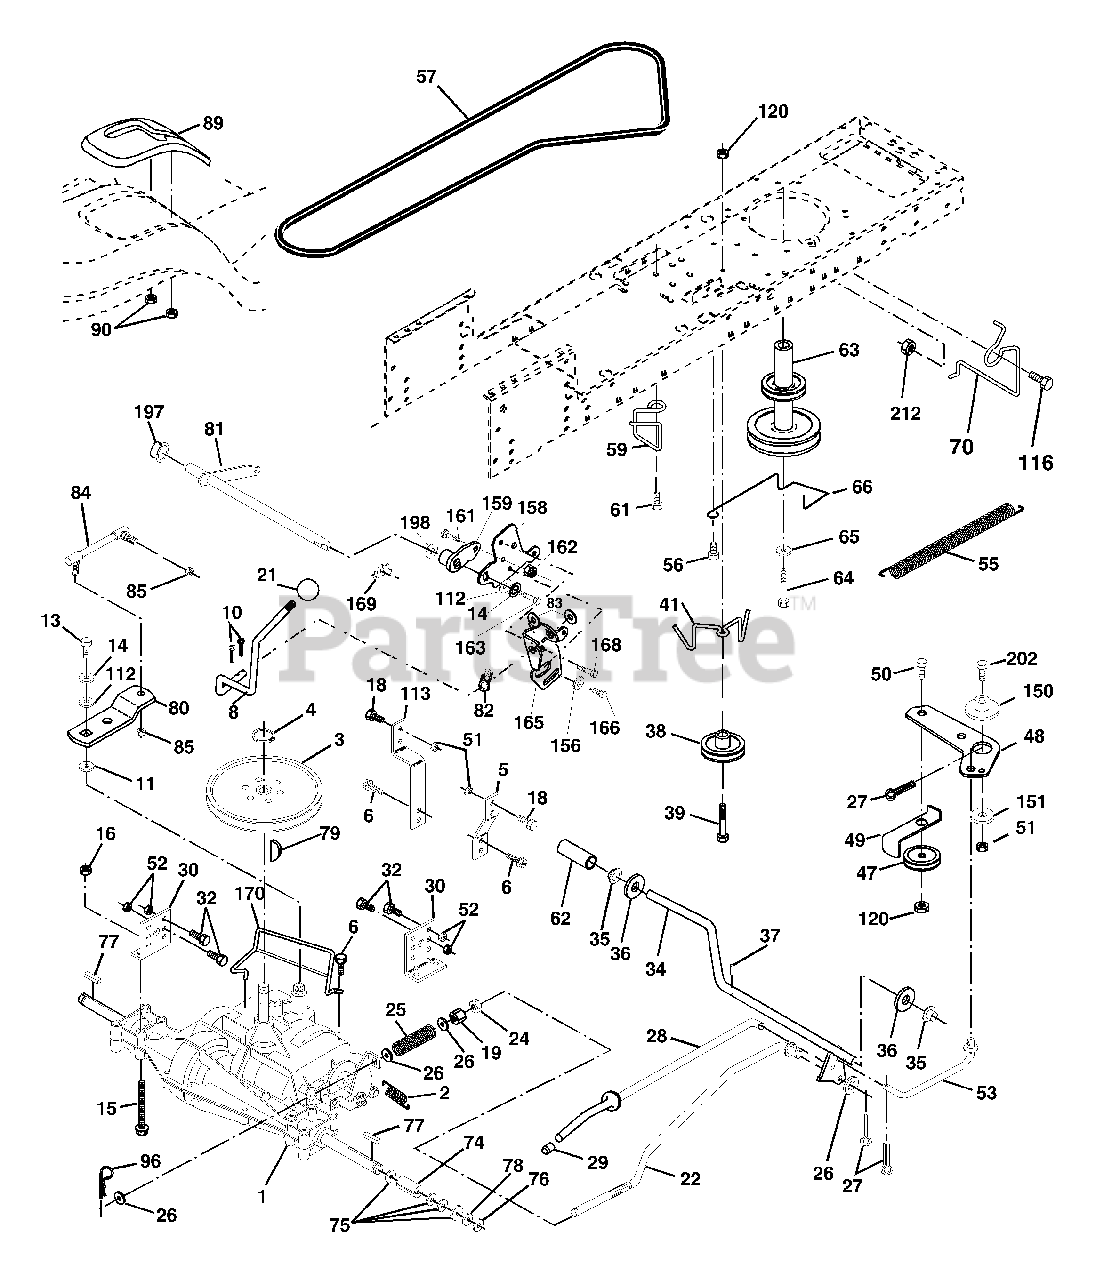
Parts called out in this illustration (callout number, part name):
2	Spring Return Brake T/a Zinc
3	Pulley Transaxle 18" tires
4	Ring Retainer # 5100-62
5	Strap Torque 30 Degrees
6	Screw Thdrol 5/16-18 x 3/4 TYT
8	Rod Shift Fender Adjust STLT
10	Pin Cotter 1/8 x 1 Cad
11	Washer Plate Shf 388 Sq Hole
13	Bolt 1/4-28 unf Gr. 8 W/Patch
14	Washer Lock Hvy Helical 1/4
15	Bolt 5/16-18 Gr. 5
16	Nut Lock Hx W/Ins 5/16-18 unc Pl
18	Bolt, Fin Hex 3/8-16 unc x 1 Gr. 5
19	Nut Lock 3/8-16 unc
22	Rod Brake Blk Zinc 26 840
24	Nut Hex Jam 3/8-16 unc
25	Spring Rod Brake 2 00 Zinc
26	Washer 13/32 x 13/16 x 16 Ga
27	Pin Cotter 1/8 x 3/4 Cad
28	Rod Brake Parking LT/YT
29	Cap Brake Parking Black
30	Bracket Mtg Transaxle
32	Bolt Hex Hd 5/16-18 unc x 3/4
34	Shaft Asm Pedal Foot
35	Bearing Nylon Blk 629 Id
36	Washer 21/32 x 1 x 16 Ga
37	Pin Roll 3/16 x 1"
38	Pulley Composite
39	Bolt Rdhd 3/8-16 x 2-3/4 Gr. 5
41	Keeper Belt Idler Flat
47	Pulley Idler V Groove Plastic
48	Bellcrank Clutch Grnd Drv Stl
49	Retainer Belt Style Spring
50	Bolt Carr. sh 3/8-16 x 1-1/2 Gr. 5
51	Nut Crownlock 3/8-16 unc
52	Nut Crownlock 5/16-18 unc
53	Link Clutch
55	Spring Return Clutch 6 75
56	Screw 3/8-16 x 1-1/4
57	V-Belt Ground Drive 95 25
59	Keeper Belt Span Ctr
61	Screw 3/8-16 x .875
62	Cover Pedal
63	Engine Pulley LT/YT
64	Bolt Hex
65	Washer Lock Hvy Hlcl Spr 7/16
66	Keeper Belt Engine Foolproof
70	Guide Belt Mower Drive RH
74	Spacer Axle
75	Washer 25/32 x 1 1/4 x 16 Ga.
76	E-ring #5133-75
77	Key Square 2 0 x 1845/ 1865
78	Washer 25/32 x 1-5/8 x 16 Ga.
79	Key Woodruff #9 3/16 x 3/4
81	Shaft Asm Cross Tapered DA/PR 18"
82	Spring Torsion T/a
83	Washer 17/32 x 3/4 x 16 Ga.
84	Transaxle Link
85	Nut Lock Center 1/4 - 28 FNTHD
89	Console Shift STLT
90	Nut Self-thd Wsh-hd 1/4 Zinc
96	Retainer Spring 1"
112	Washer 9/32 x 3/4 x 10 Ga.
113	Strap Torque LT
116	Bolt Rdhd Sq Neck 3/8-16 x 1
120	Nut Lock Flg. 3/8-16
150	Spacer Retainer
151	Washer 13/32 x 2 x 10 Ga.
156	Washer Srrted 5/16 ID x 1.125
158	Bracket Shift Mount
159	Hub Shift
161	Bolt Rdhd Sqnk 1/4-20 x 3/4 Gr. 5
162	Nut Crownlock 1/4-20 unc
163	Bolt Hex Fin 1/4-20 unc x 1 Gr. 5
165	Bracket Pivot Lever
166	Screw 5/16-18 x 5/8
168	Bolt Shoulder 5/16-18 x .561
169	Plate Fastening STLT/CRD
170	Keeper Belt T/A
197	Nyliner Snap-In 5/8" ID
198	Washer Nyl 7/8 Id x .105" Hyd
202	Bolt 3/8-16 x 1-3/4 Gr 5
212	Nut Hex Flg Lock
